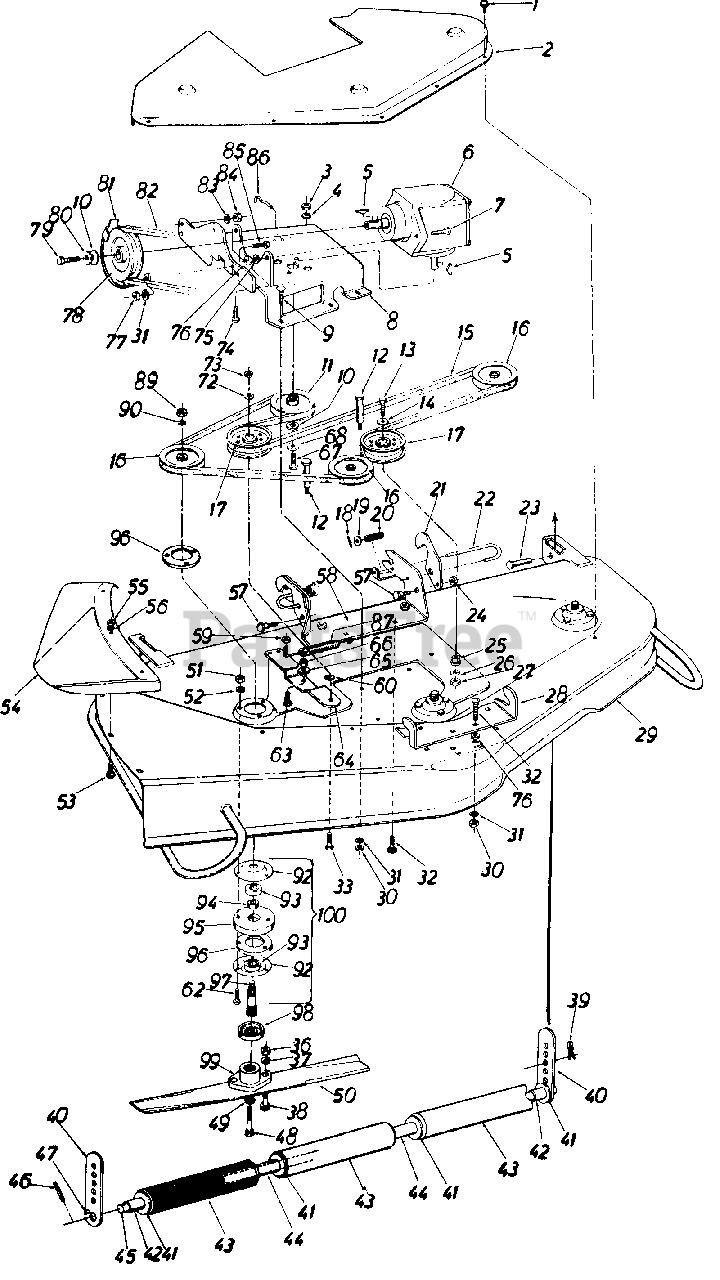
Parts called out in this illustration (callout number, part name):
1	Hex "B"-Tapp Scr. 1/4-20 x 3/8" Lg.
2	Belt Cover
3	Hex Nut 5/16-29 Thd.*
4	L-Wash. 5/16" Scr.*
5	#9 Hi-Pro Key 3/16 x 3/4" Dia.
6	Right Angle Gear Box
7	Hex Scr. 3/8-16 x 1.25" Lg.*
8	Deck Bracket Ass'y.
9	Carriage Bolt 5/16-18 x .75" Lg.*
10	Fl.-Wash. 5/16" I.D. x 1.12 O.D.
11	Deck Pulley-Out Put
12	Shoulder Scr 1/2" Dia. x 2.00" Lg.
13	Hex Scr. 3/8-16 x 2.25" Lg.
14	Fl-Wash. 3/8" I.D.
15	"V"-Belt 1/2" x 108" Lg.
16	Deck Pulley
17	Idler Pulley 4.62" O.D.
18	Roll Pin 1/8" Dia.
19	Fl-Wash. .406 I.D. x .734 O.D.
20	Compression Spring .47 O.D. x 1.93
21	Hanger Lock
22	Release Pin
23	Clevis Pin .500" Dia.
24	HexCent. L.-Nut5/16-18 Thd.
25	Idler Adapter
26	L-Wash. 3/8" Scr.
27	HexCent. L-Nut 3/8-2 Thd.
31	L.-Wash.
32	Carriage Bolt 5/16-18 x 1.00" Lg.*
33	Hex Scr. 5/8-18 x 1.31" Lg.
36	Hex Cent. L.-Nut 5/16-24 Thd.
37	L.-Wash. 5/16" Scr.*
38	Hex Scr. 5/16-24 x 1.00 Lg.*
39	Internal Cotter Pin
41	Fl.-Wash. .75 I.D. x 1.50 O.D.
42	Spacer .758" Dia. x 1.25 O.D. x .530
43	Roller
46	Roll Pin 3/16" Dia. x 1.25" Lg.
47	Spring-Pin Spiral 1/4" Dia. x 1.00" Lg.
48	Thread Roll Hex Scr. 3/8-24 x .75" Lg.
49	L.-Wash. 5/16" Scr. Heavy Duty
50	Blade 17"
51	Hex Cent. L-Nut 5/16-24 Thd.
52	L.-Wash. 5/16" Scr.
53	Carriage Bolt 5/16-18 x .75" Lg.*
55	Hex Nut 5/16-18 Thd.*
56	L.-Wash. 5/16" Scr.*
57	Shoulder Bolt
60	Fl-Wash. .62 I.D.
62	Hex Scr. 5/16-24 x 1.00" Lg.*
63	Hex Scr. 5/16-18 x 1.00" Lg.*
64	Idler Bracket Ass'y.
65	Shoulder Nut
66	Hex Cent. L-Nut 5/16-18 Thd.
67	Hex Scr. 5/16-18 x 2.00" Lg.*
68	Belleville Wash.
72	Fl-Wash. .62 I.D.
73	Hex Cent. L.-Nut 5/8-18 Thd.
74	Hex Scr. 1/4-20 x 1.25" Lg.
75	L-Wash. 3/8" Scr.*
76	Hex Nut 3/8-16 Thd.*
77	Hex Nut 5/16-18 Thd.*
78	Pulley 4.75" O.D.-Input
79	Hex Scr. 5/16-18 x 2.00" Lg.*
80	Belleville Wash.
81	Belt Guard
82	"A"-Section "V"-Belt 1/2" x 56" Lg.
83	L.-Wash. 5/16" Scr.*
84	Hex Nut 5/16-18 Thd.*
85	Hex Scr. 5/16-18 x .75" Lg.*
86	Spri ng Tension Anchor Pin
87	Extension Spring
89	Hex Jam Nut 5/8-18 Thd.
90	L.-Wash. 5/8 I.D.
92	Bearing Housing
93	Ball Bearing
94	Spacer
95	Spindle Spacer Plate
96	Reinforcement Plate
97	Spindle
98	Bearing Shield
99	Blade Adapter
100	Deck Spindle Ass'y.
12649-0638	GUARD-CHUTE - MTD/TROY-BILT RED (0638)
12649-0648	GUARD-CHUTE - TECH GRAY (0648)
12650-4008	Height Adjuster - WINE RED (4008)
